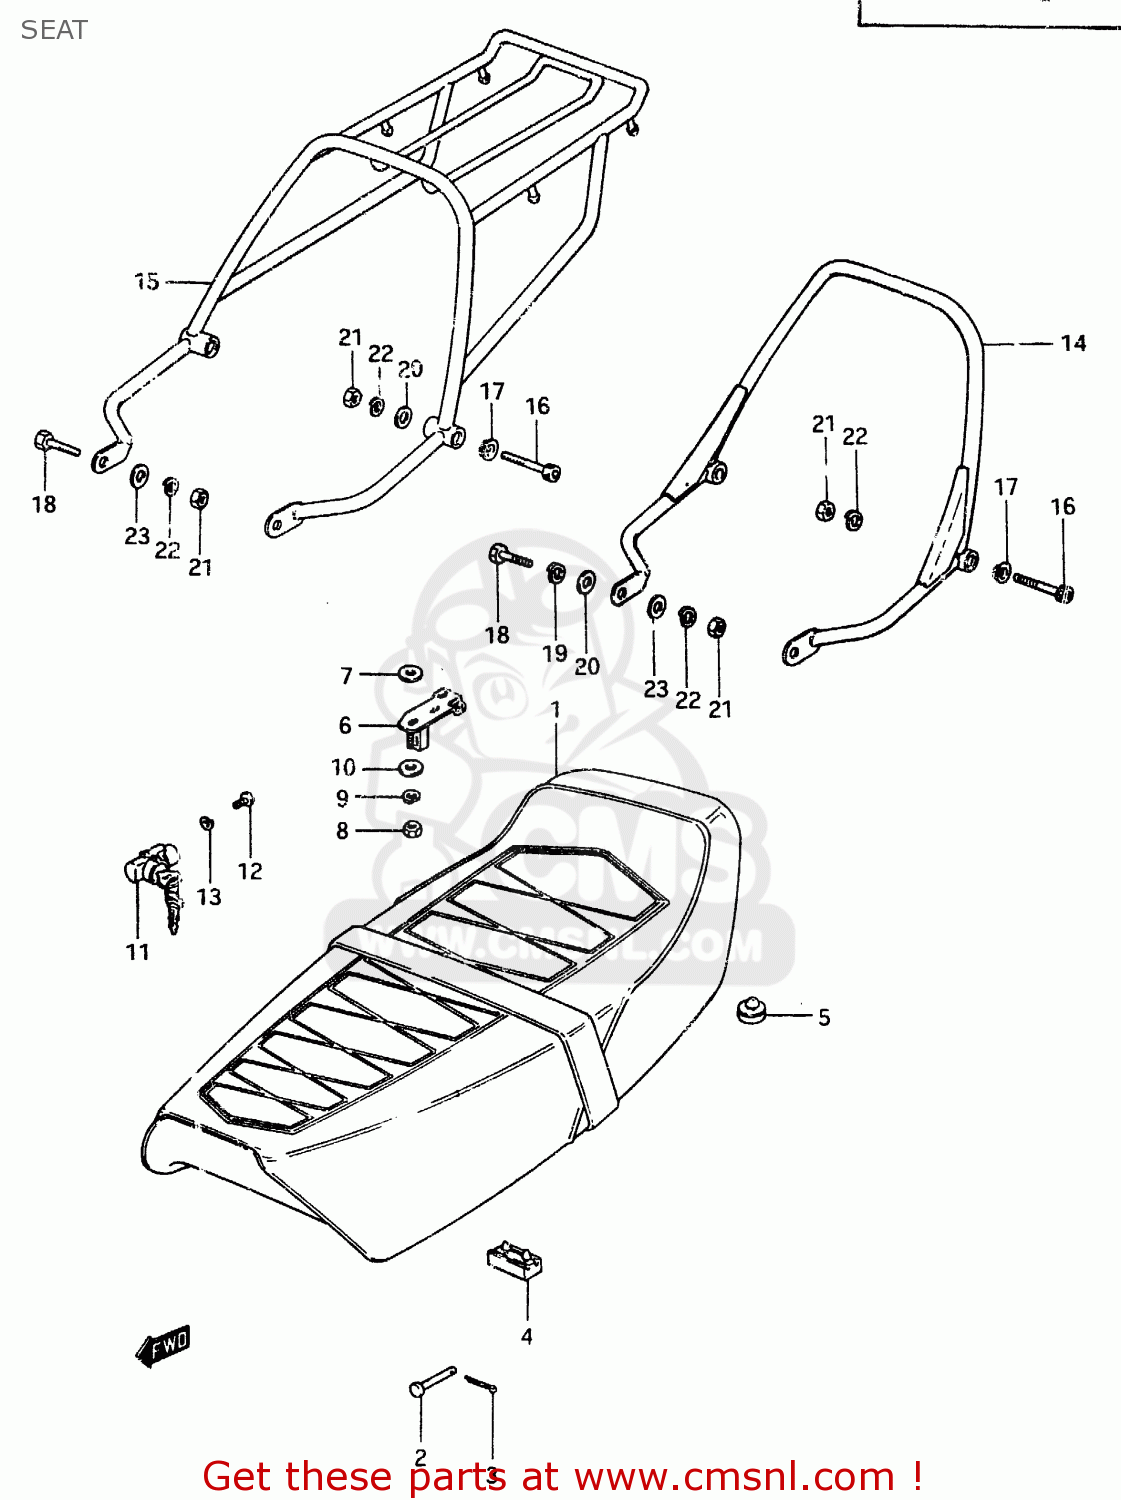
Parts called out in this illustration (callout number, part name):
1	SEAT ASSY (BLACK)
2	PIN
3	PIN
4	CUSHION
5	CUSHION
6	PLATE, SEAT LOCK
7	WASHER(8.5X18X1)
8	NUT
9	LOCK WASHER
10	WASHER
11	LOCK ASSY,SEAT
12	SCREW
13	LOCK WASHER
14	HANDLE, PILLION RIDER
15	CARRIER, SPORTS
16	BOLT, REAR
17	WASHER
18	BOLT 8X50
19	LOCK WASHER
20	WASHER
21	NUT 8MM
22	LOCK WASHER
23	WASHER
